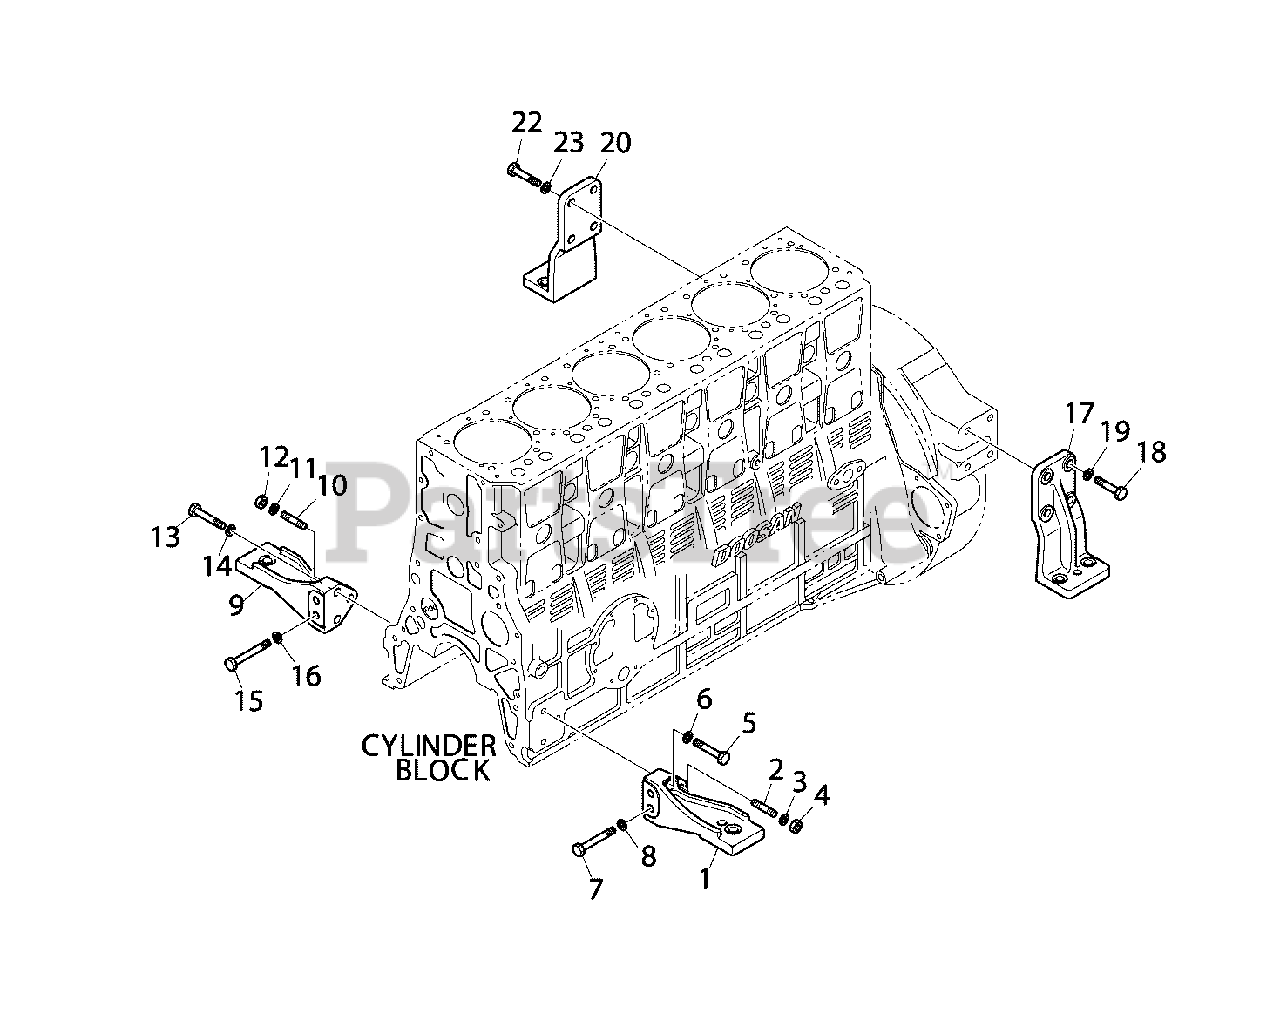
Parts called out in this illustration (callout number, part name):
1	* MOUNT, ENGINE
2	* BOLT, STUD
3	* WASHER, SPRING
4	* NUT, HEX
5	* BOLT, HEX
6	* WASHER, SPRING
7	* BOLT, HEX
8	* WASHER, SPRING
9	* MOUNT, ENGINE
10	* BOLT, STUD
11	* WASHER, SPRING
12	* NUT, HEX
13	* BOLT, HEX
14	* WASHER, SPRING
15	* BOLT, HEX
16	* WASHER, SPRING
17	* BRACKET, R/MOUNT
18	* BOLT, HEX
19	* WASHER, SPRING
20	* BRACKET, R/MOUNT
22	* BOLT, HEX
23	* WASHER, SPRING
